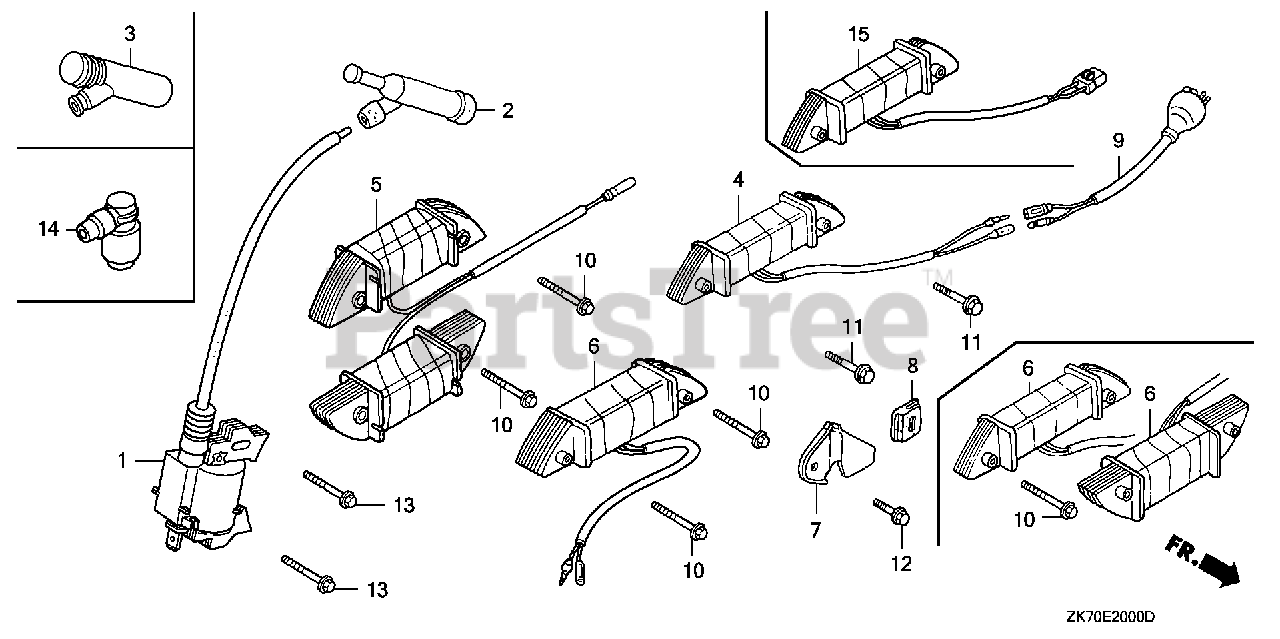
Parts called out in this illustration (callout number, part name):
1	COIL ASSY., IGNITION Use up to Engine SN 1530314.
2	CAP ASSY., NOISE SUPPRESSOR (Honda Code 3526837). (NICHIWA Y-EZ RTFM256)
13	BOLT, FLANGE (6X25) Use up to Engine SN 2056819.
